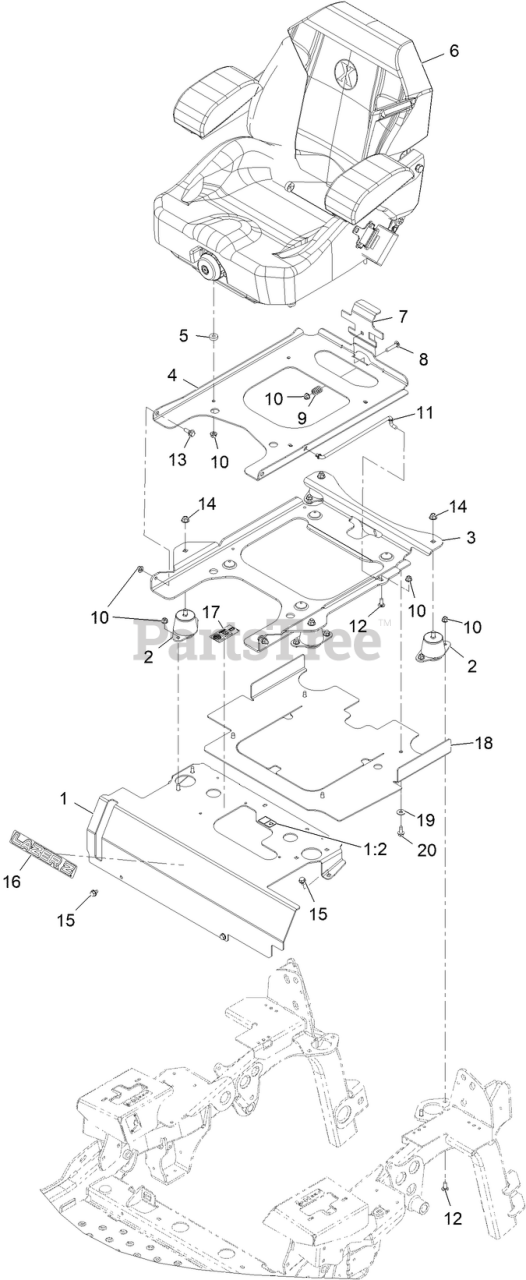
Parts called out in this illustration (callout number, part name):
1	MOUNT-SEAT W/DECALS
1:2	DECAL-WARNING
2	ISOLATOR-SEAT
3	Plate,Tilt Seat Support
4	PLATE-FRAME, SEAT
6	KIT-SUSPENSION SEAT
7	PLATE, SEAT LATCH
8	BOLT-CARR
9	SPRING-COMPRESSION
10	NUT-HF, NI
11	ROD-PROP
12	SCREW-CARR
13	SCREW-SHOULDER
14	NUT-HF, NI
16	DECAL, LAZER MODEL
17	DECAL-TRANS FLUID
18	SHIELD-HEAT
19	WASHER-FLAT
20	Screw-HWH 5/16-18 X 3/4 Tf
